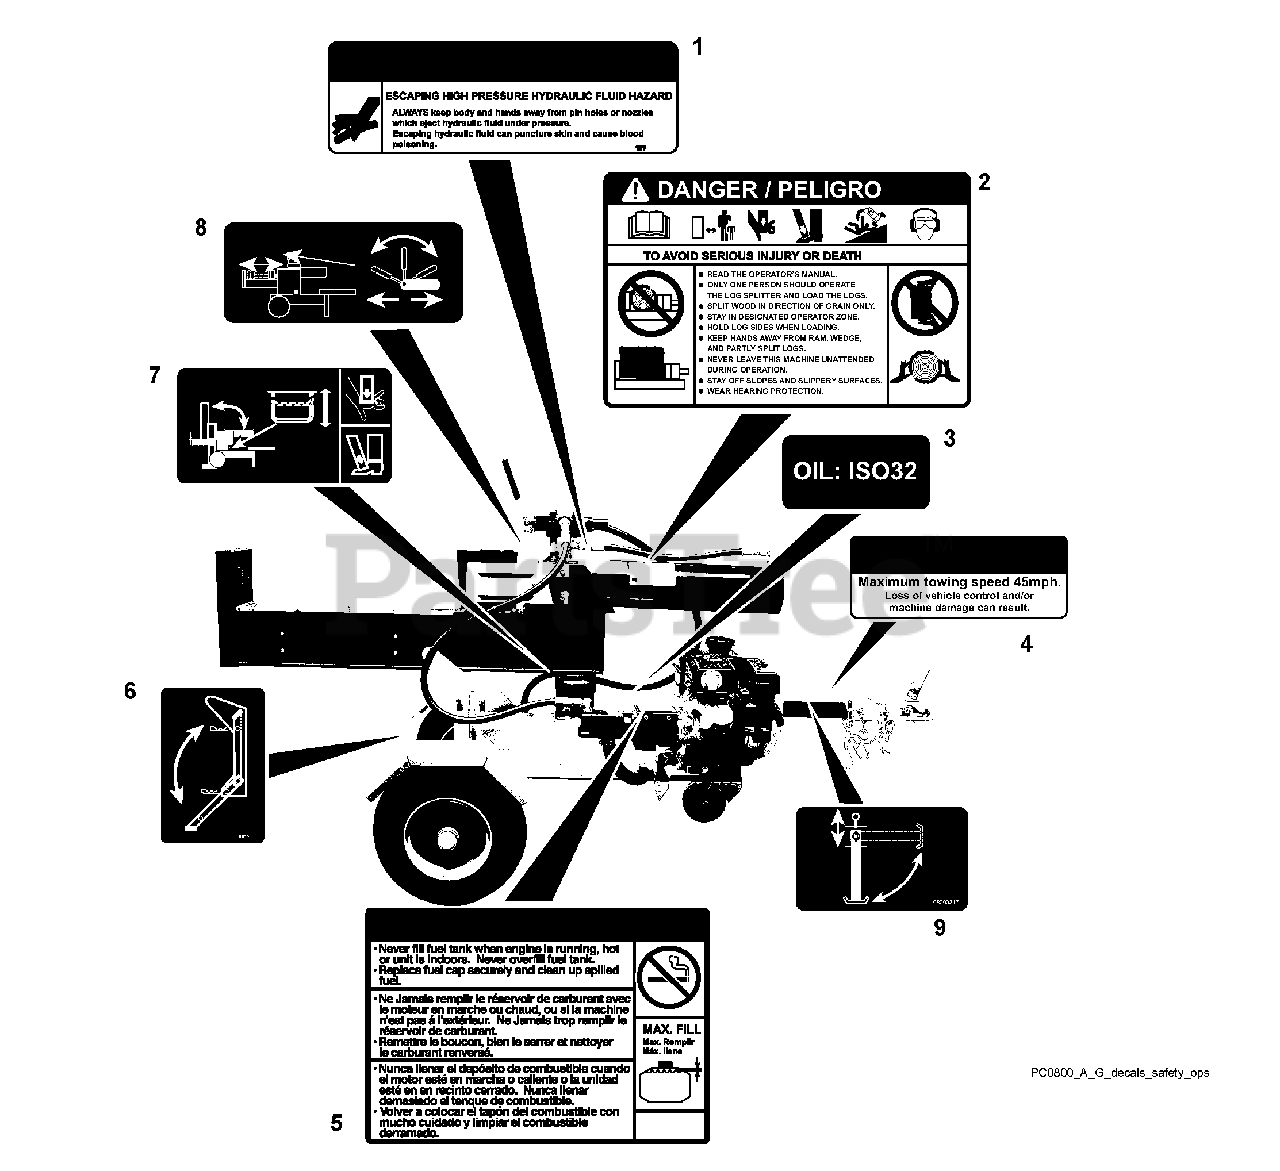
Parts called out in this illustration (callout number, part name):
1	Decal, Log Splitter Hydraulic Warning
2	Decal, Log Splitter Danger
3	Decal, Log Splitter Hydraulic Oil
4	Decal, Log Splitter Towing
5	Decal, Log Splitter Gas Caution
6	Decal, Log Splitter Rear Stand
7	Decal, Log Splitter Tilt Operation
8	Decal, Log Splitter Ram Operation
9	Decal, Log Splitter Front Stand
10	Decal Sheet (Includes Items 1 – 9)
